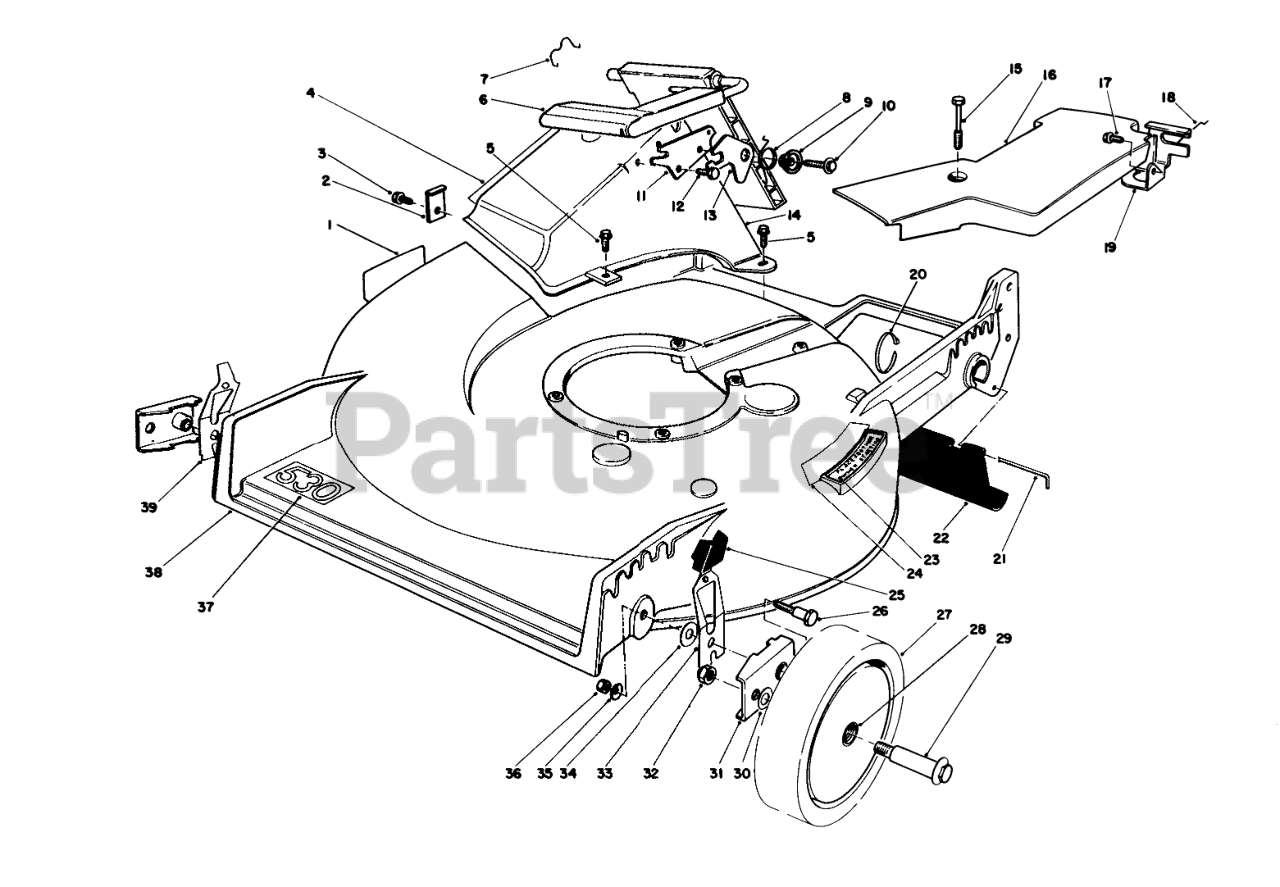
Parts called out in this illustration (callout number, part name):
1	DECAL-DANGER
2	TUNNEL CLIP
3	SCREW
4	Decal-Attention
5	SCREW-HWH
6	Discharge Door Assembly
7	DOOR RET SPRING
8	TORSION SPRING
9	DOOR SPACER
10	SCREW-HWH
11	DOOR LATCH PLATE
12	SCREW-PLASTITE
13	SAFETY LATCH
14	Tunnel Discharge
15	SCREW-HHFTF
16	Cover-Belt
17	SCREW-HWHTF
18	RETAINER-CABLE
19	Bracket-Traction Adj.
20	TIE-CABLE
21	ROD-SHIELD
22	SHIELD-TRAILING
23	STEP PAD DECAL
24	Decal-Place Foot Here
25	KNOB-ARM
26	PIVOT SCREW
27	Wheel & Tire Assembly (Incl. Ref. #28)
28	BUSHING
29	BOLT-WHEEL
30	WASHER
31	HP PIVOT ARM ASM
32	Nut
33	L. HP SPRING ARM ASM
34	WASHER-PIVOT
35	WASHER-BELLEVILLE
36	NUT-LOCK, NI
37	Decal-530
38	21" Housing (Incl. Ref. #1)
39	R HP SPRING ARM ASM
